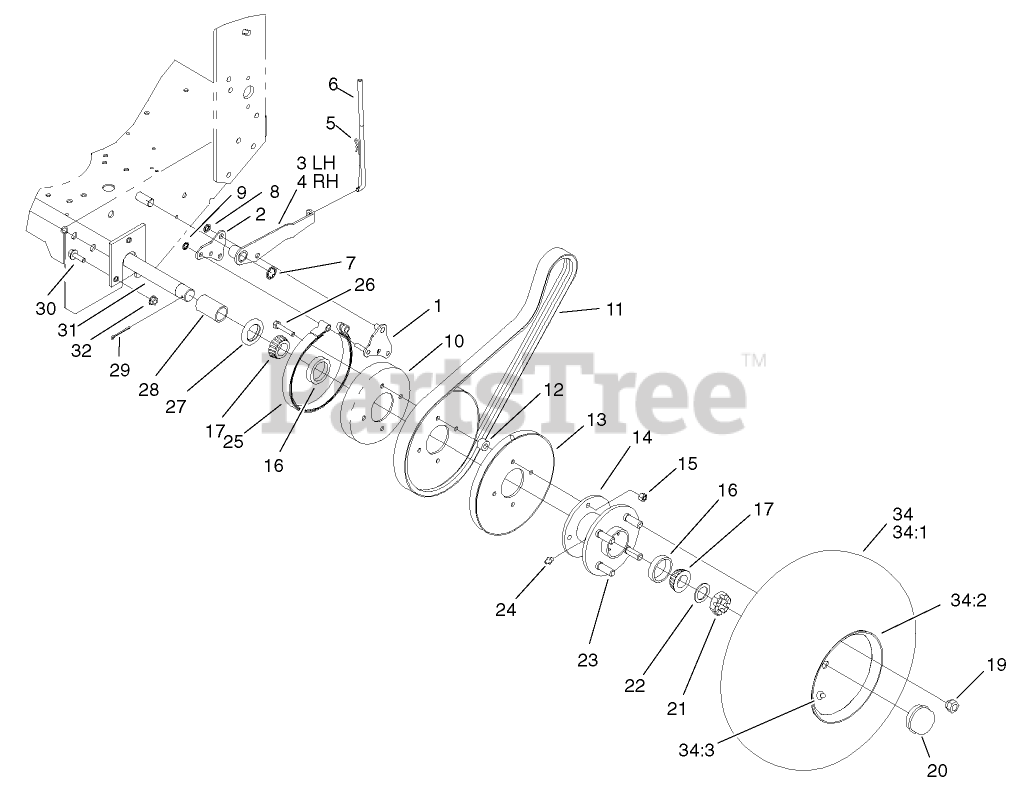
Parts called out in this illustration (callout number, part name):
1	BRAKE LINK ASM
2	PLATE-LINK, BRAKE
3	LH BRAKE ARM ASM
4	RH BRAKE ARM ASM
5	PIN-COTTER
6	ROD-BRAKE
7	RING-RETAINING
8	RING-RETAINING, EXTERNAL
9	RING-RETAINING
10	DRUM-BRAKE
11	BELT-DRIVE, TRACTION
12	SPACER-PULLEY
13	PULLEY-WHEEL
14	HUB/WHEEL ASM
15	NUT-LOCK, NI
16	BEARING-CUP, TAPERED
17	BEARING-CONE, TAPERED
19	NUT-LUG
20	CAP-DUST
21	NUT-SHH
22	WASHER-SPACER
23	STUD-WHEEL
24	FITTING-GREASE
25	BAND-BRAKE
26	SCREW-HH
27	SEAL-GREASE
28	SPACER-WHEEL
29	PIN-COTTER
30	SCREW-HHF
31	AXLE ASM
32	NUT-HF
34	WHEEL AND TIRE ASM
34:3	STEM-VALVE
